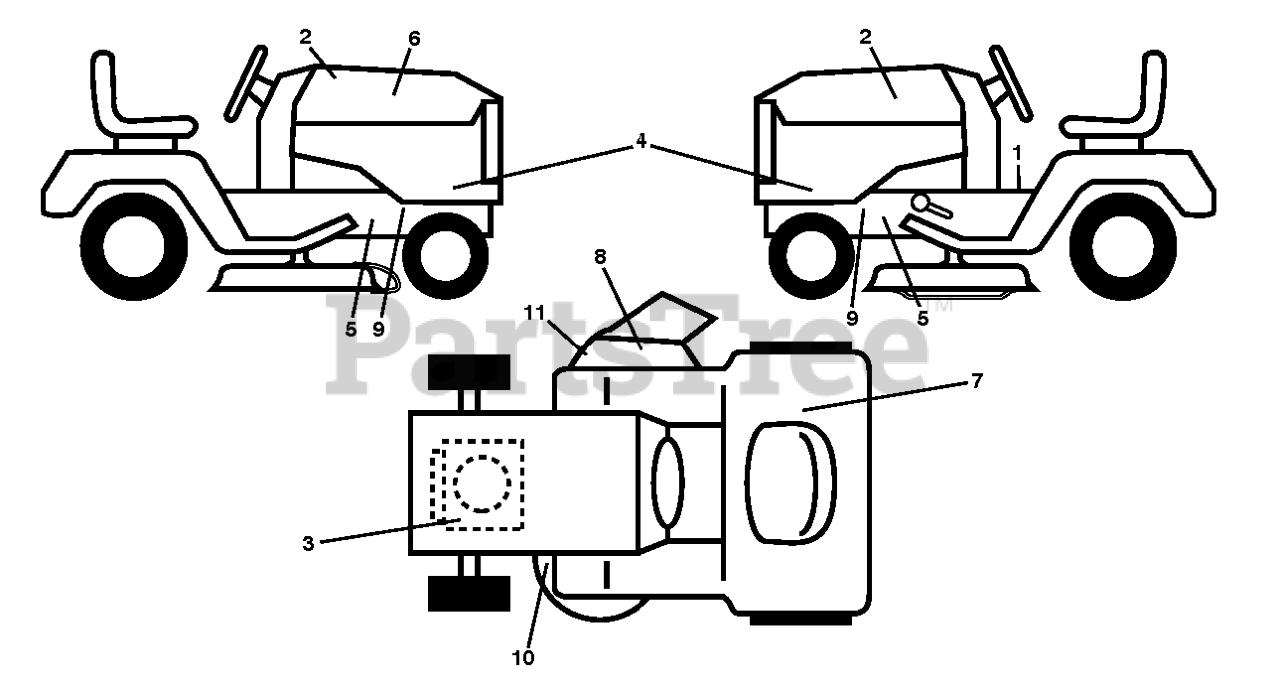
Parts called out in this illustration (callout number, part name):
1	DECAL.TRACTOR.SADDLE
2	DECAL.WB.178MM.15.HUSQ.NEWBRAN
3	DECAL.ENGINE.WARNING
5	DECAL.WARNING.HOT.MUFFLER.2021
7	Decals
8	DECAL.DECK.DEFLECTOR.WARNING
9	DECAL.WARNING.SERVCE/FIRE
10	DECAL.DECK.SCH.36,38,94.NONCR
11	DECAL.DFLCTR.WARNNG.CTFNGR.SYM
